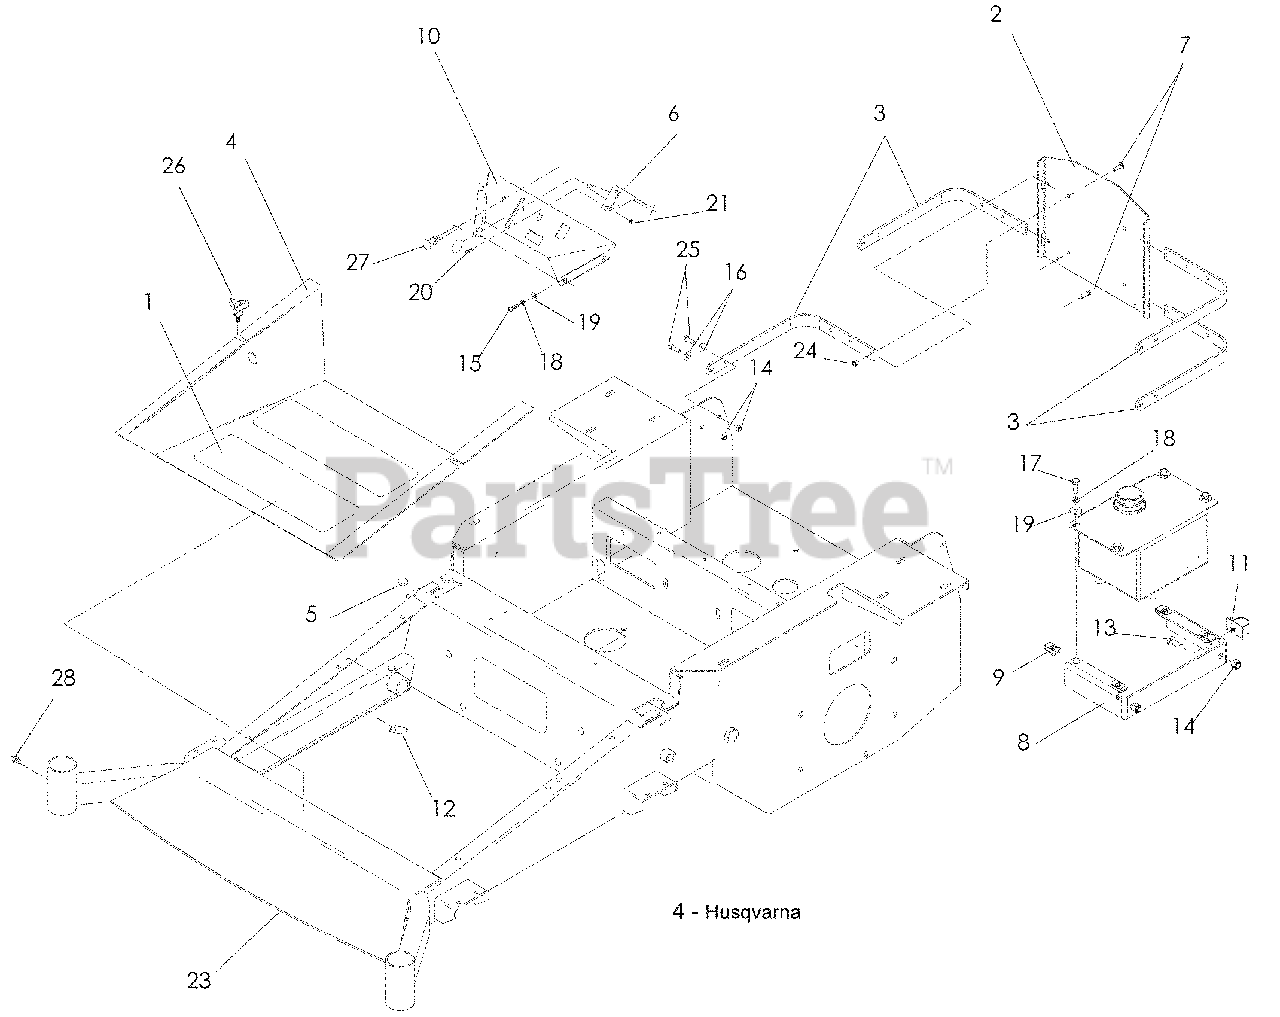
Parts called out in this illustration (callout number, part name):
1	FLOOR PAN PAD
2	XP GUARD, BLACK
3	STRAP, BLACK
4	FOOT PLATE
6	CABLE, THROTTLE
7	RHSNB 5/16-18 x ¾
8	TANK MOUNT
9	U TYPE RETAINER
11	CLIP, PUSH MOUNT
12	U CLIP 5/16-18
13	HCS 5/16-18 x ¾
14	NUT 5/16-18 HEX NYLOC
15	TFS ¼-20 x 5/8
16	WASHER 5/16 STD FLT
17	HCS ¼-20 x ¾
18	LOCKWASHER ¼
19	WASHER ¼ FLAT
20	HCS 10-24 x ½
21	NUT 10-24 NYLOC
22	WASHER 5/16 LOCK
24	NUT 5/16-18 CENTERLOCK
25	HCS 5/16-18 x 1
26	KNOB W/STUD
27	CHOKE CONTROL
28	ZERK
